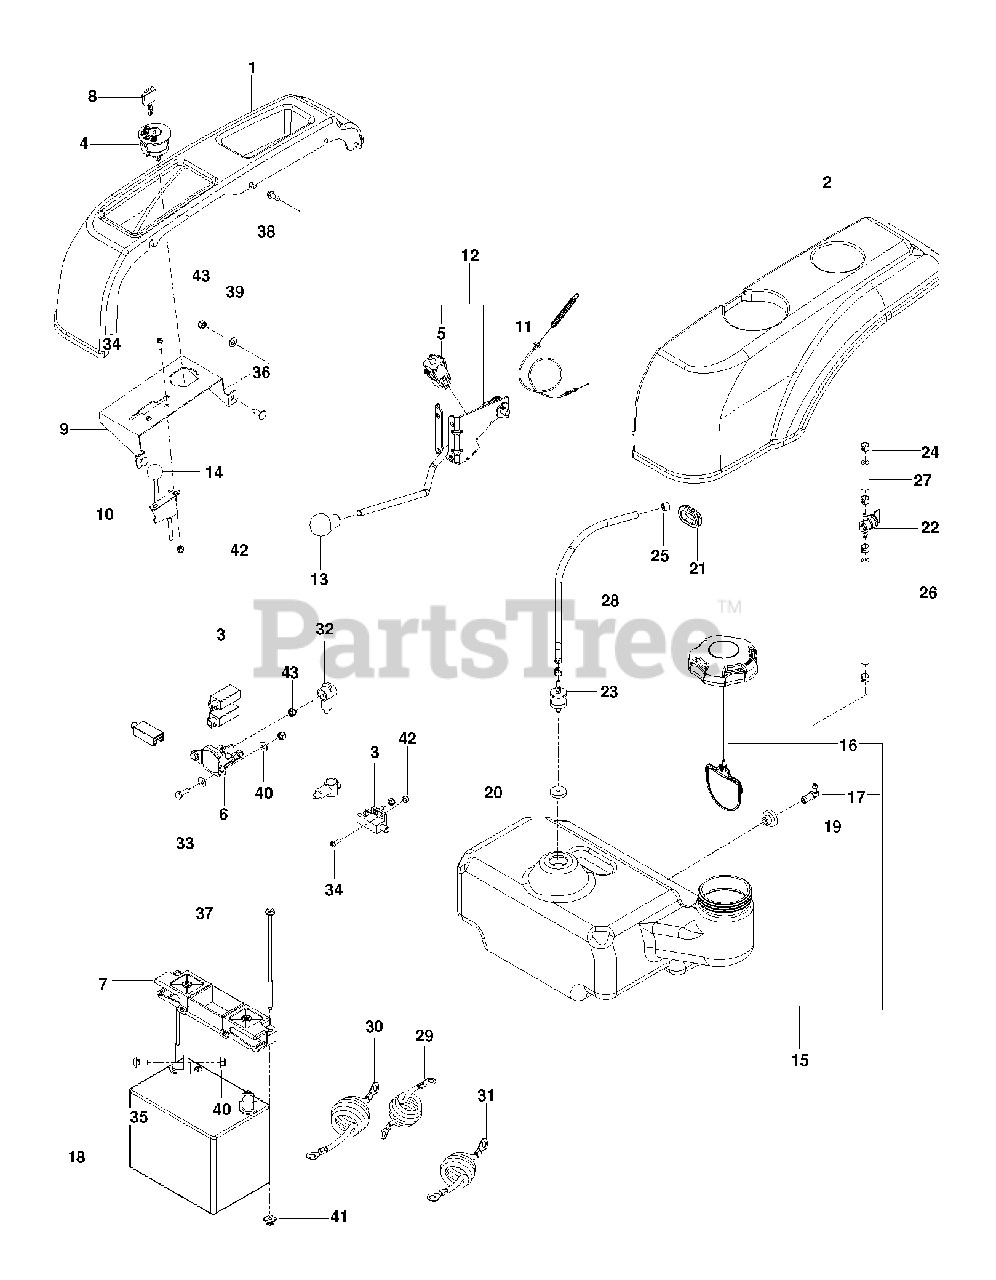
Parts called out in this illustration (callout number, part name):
1	FENDER, RZ 30/38 RT
2	FENDER, RZ 30/38 LT
3	SWITCH INTERLOCKT
4	RP IGNITION SWITCH
5	SWITCH INTERLOOK PUSH-IN
7	BATTERY HOLD DOWN
8	KEY MLD GEN DELTA
9	MOUNT, CONTROLS, BLK
10	CABLE, THROTTLE
11	CABLE.CLUTCH.38".SERVICE
12	ASM, CLUTCH ENGAGE W/CABLE
13	KNOB - SHIFT
14	KNOB.ROUND.BALL.BLACK
15	FUEL TANK ASM SMALL
16	CAP, FUEL
17	STEM, FUEL TANK
18	BATTERY, 12 V 330 AMP
19	RUBBER GROMMET
20	GROMMET, CHECK VALVE
21	RUBBER GROMMET
22	FUEL VALVE
23	VALVE.FUEL.CHECK
24	HOSE CLAMP
25	CLAMP, HOSE
26	HOSE 1/4 X 8
27	HOSE 1/4 X 2"
28	HOSE, FUEL, 3/16" X 20"
29	POST.CABLE LONG
30	CABLE POSITIVE, LONG
31	BATTERY CABLE, NEGATIVE
32	TERMINAL COVER
33	HCS 1/4C X 3/4 HCS
34	SCREW #10-24 X 5/8
35	BOLT 5/16C X 3/4" CARRIAGE
36	RHSNB 1/4C X 3/4
37	Bolt, 1/4-20 X 7.5
38	SCREW 1/4 X 5/8
39	WASHER 1/4 SAE
40	5/16-18 NYLOC FLANGE NUT
41	PUSH NUT-NYLON
42	NUT 10-24 NYLOC
43	RP_NUT 1/4-20 NYLOC
